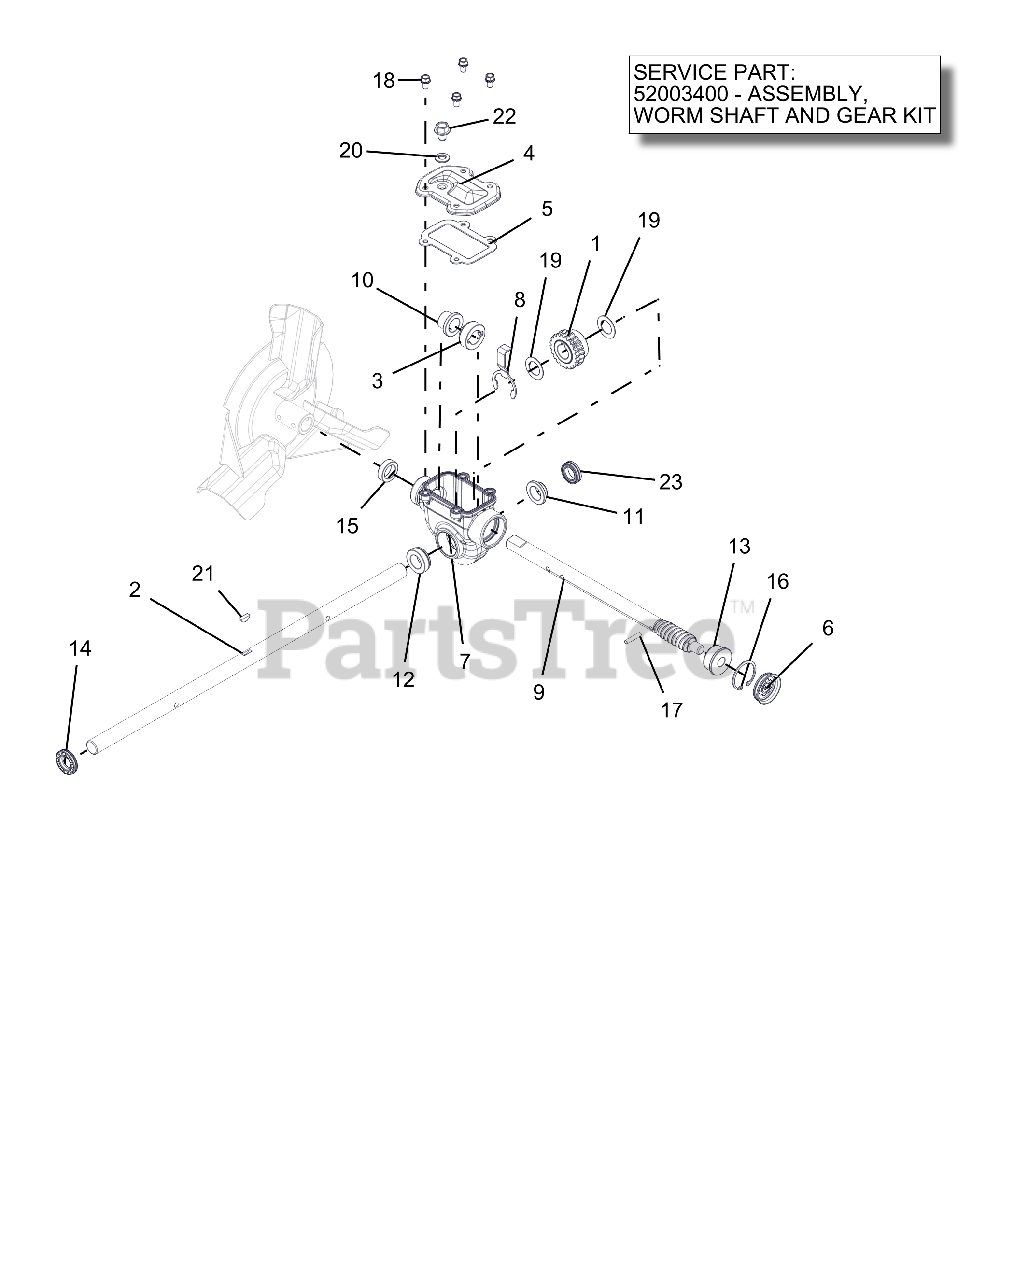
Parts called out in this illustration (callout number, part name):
1	WORM GEAR
2	SHAFT, RAKE - 22" (.750 DIA)
3	THRUST COLLAR, .75" ID SLIPFIT
4	COVER, TOP - COMPACT
5	GASKET, TOP - COMPACT GEARCASE
6	COVER, GEAR CASE 1.50"
7	GEARCASE, COMPACT ALUMINUM
8	BUSHING RETAINER, COMPACT
9	SHAFT, WORM - COMPACT
10	BSHG-FLG .755X.878X.75X1.25
11	BSHG-FLG .755X.878X.424X1.25
12	BSHG-FLG COMPACT, RIGHT
13	BSHG-FLG .503X1.303X.62X1.465
14	SEAL-OIL .748X1.300X.250 TBC29
15	SEAL-OIL .748X1.125X.312 TB2-H
16	RG-RTNG-INT 1.500X.050
17	PIN-STR .188X1.00 6150
18	BOLT, SEMS .25-20X.50 GR5 YWZC
19	WSHR-FL-STL .760X1.225X.032 YZ
20	WSHR-BND-SEAL .38X.75X.11 GALV
21	KEY-WDRF .19X.63 HRD #61
22	@SCR-ROLOK .38-16X.50 HWH YWZC
23	SEAL-OIL .748X1.125X.312 TBC29
24	SHAFT AND WORM GEAR ASSEMBLY
